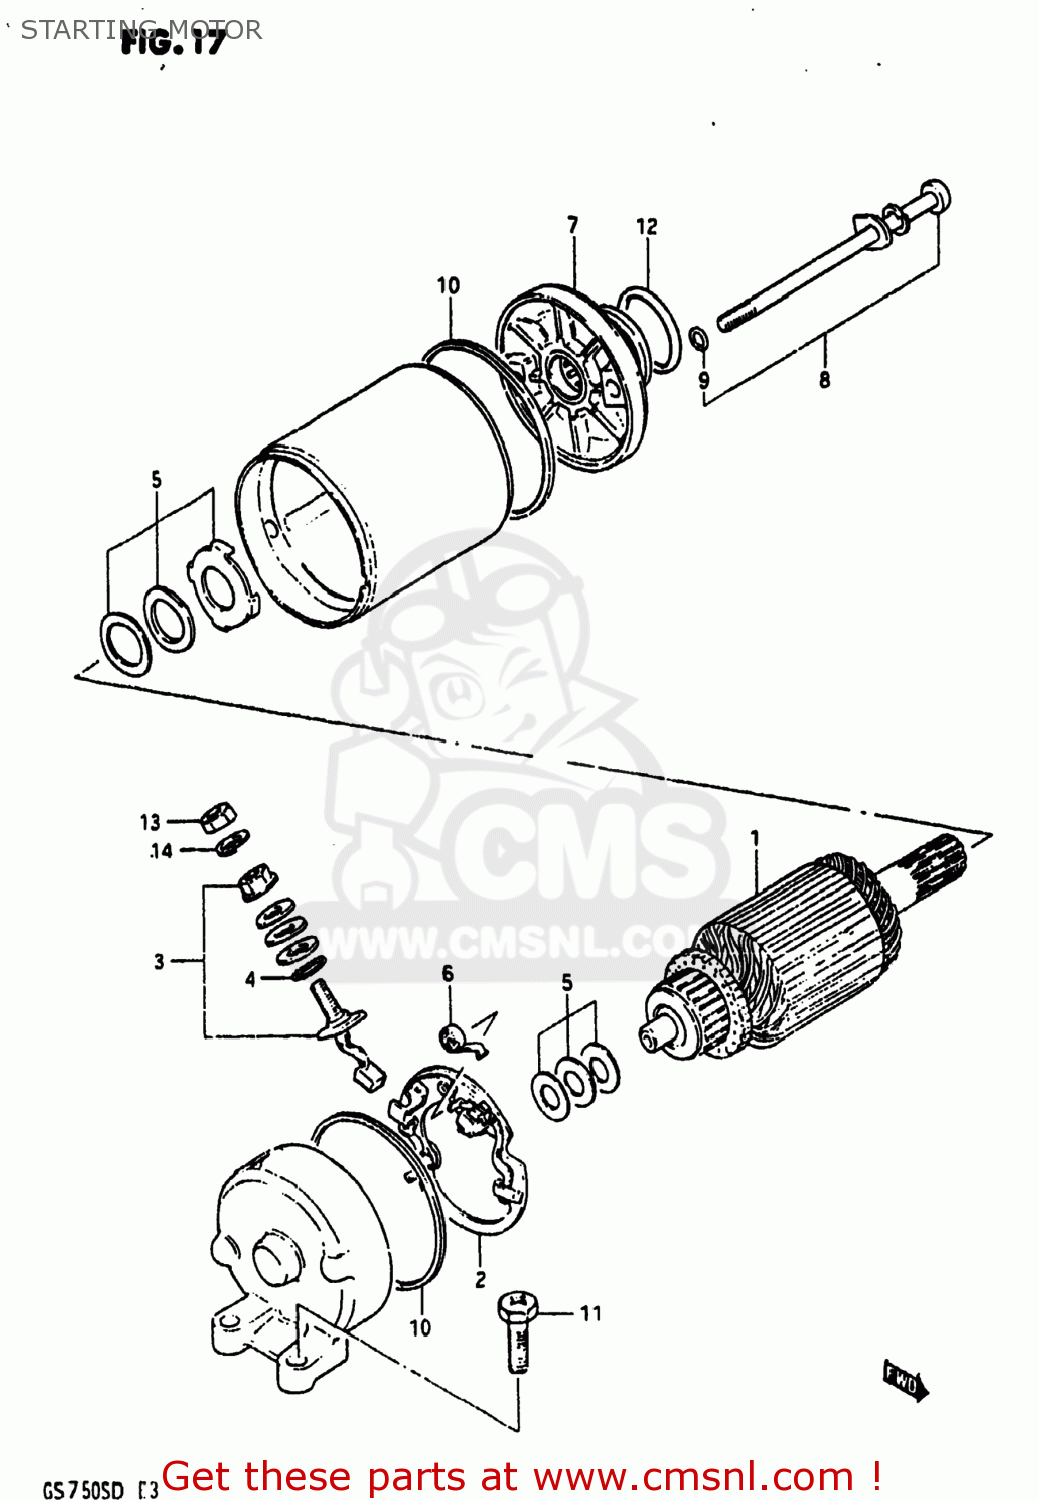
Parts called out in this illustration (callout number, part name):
1	ARMATURE
2	HOLDER SET,BRUSH(-)
3	TERMINAL SET,BRUSH,PLUS
4	O RING
5	SHIM SET,STARTING MOTOR
6	SPRING,BRUSH
7	BRACKET SET,STARTING MOTOR
8	BOLT SET,STARTING MOTOR
9	O RING
10	O RING
11	SCREW (6X25)
12	O RING(D:2,ID:24.5)
13	NUT 6MM
14	LOCK WASHER
